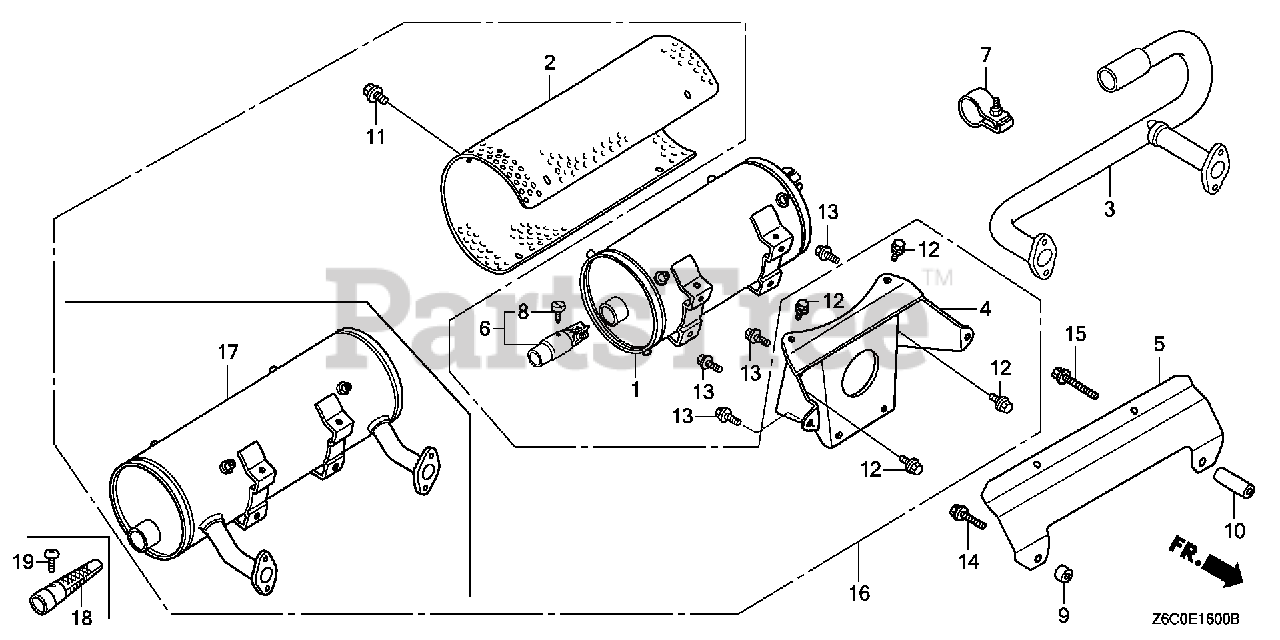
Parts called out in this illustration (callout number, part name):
1	MUFFLER (HIGH)(NELSON)(BLACK MUFFLER) (SHIFT18300-ZJ1-881) (IF N/A - #18300-ZJ1-891 LT.)
2	PROTECTOR, MUFFLER (HIGH) (FUTABA) (FOR BLACK MUFFLER)
2	PROTECTOR, MUFFLER (HIGH) (FUTABA) (FOR SILVER MUFFLER)
3	PIPE, EX. (HIGH-R) (FOR BLACK MUFFLER)
4	STAY, MUFFLER (HIGH-FUTABA) (FOR SILVER MUFFLER)
4	STAY, MUFFLER (HIGH-NELSON) (FOR BLACK MUFFLER)
6	ARRESTER, SPARK (FOR BLACK MUFFLER)
7	BAND ASSY. (FOR BLACK MUFFLER) (NOT AVAILABLE)
8	SCREW (NELSON) (FOR BLACK MUFFLER)
11	BOLT, FLANGE (6X8)
12	BOLT, FLANGE (8X14)
13	BOLT, FLANGE (8X20)
16	MUFFLER ASSY. (HIGH-R) (FUTABA) (SILVER MUFFLER)
17	MUFFLER COMP. (HIGH-R) (FUTABA) (SILVER MUFFLER)
18	ARRESTER KIT (HIGH)
18	ARRESTER, SPARK (FOR SILVER MUFFLER)
19	SCREW, TAPPING (5X8) (FOR SILVER MUFFLER)
